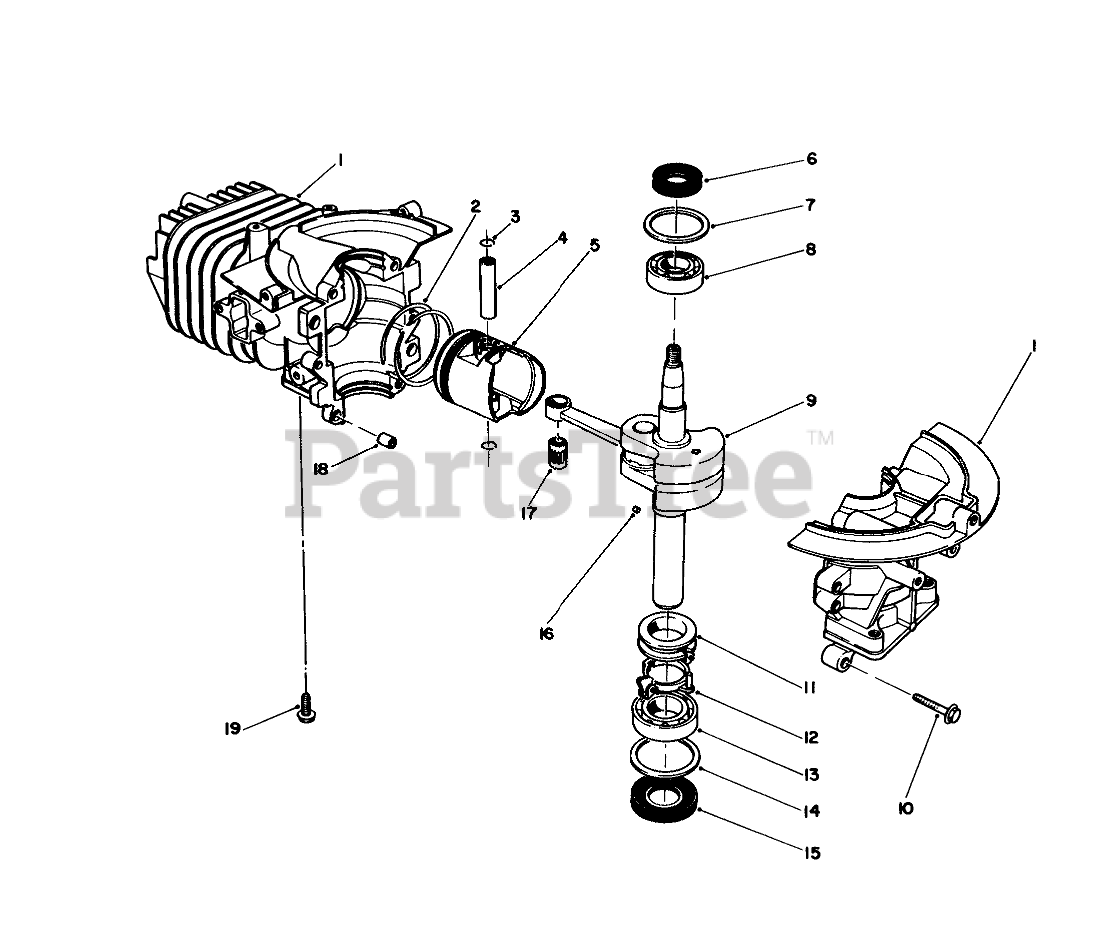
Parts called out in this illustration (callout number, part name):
1	CYL/CRANKCASE ASM
2	RING SET
4	PISTON
5	Piston
6	OIL SEAL
7	WASHER-UPPER
8	BEARING-UPPER
9	CRANKSHAFT
11	SPACER
12	BRACKET
13	LOWER BRG
14	WASHER-LOWER
15	SEAL-OIL
17	BEARING
